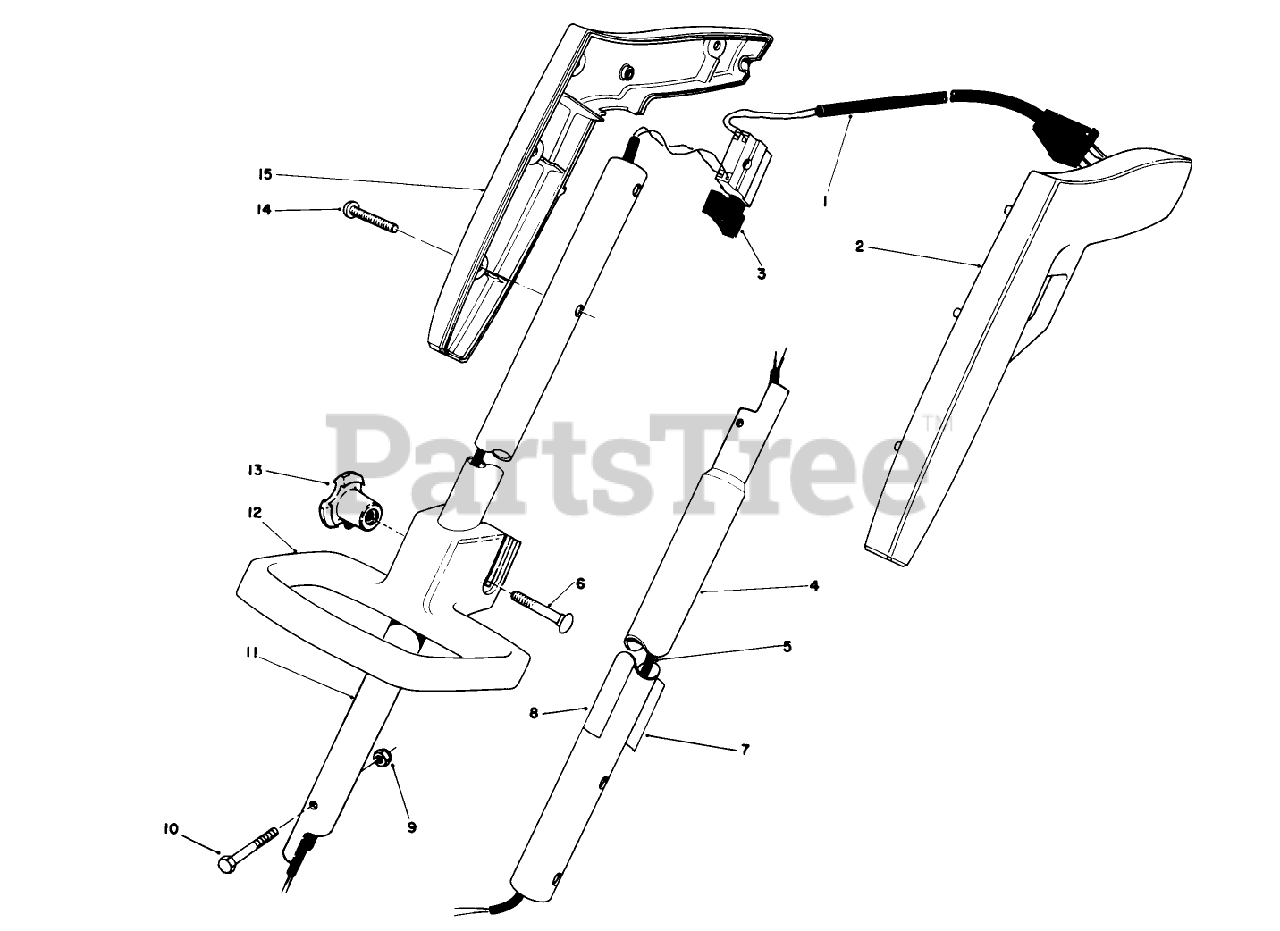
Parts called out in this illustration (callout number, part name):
1	Power Cord
2	Grip L.H.
3	SWITCH SINGLE SPEED
4	Tube-Lower
5	Wiring Harness
6	BOLT-CARR
7	REP. SERIAL PLT
8	Decal
9	NUT-LOCK, NI
10	HEX HD MACHINE SCREW
11	Tube-Upper
12	ADJUSTABLE HANDLE
13	Knob
14	Screw
15	R.H. GRIP
